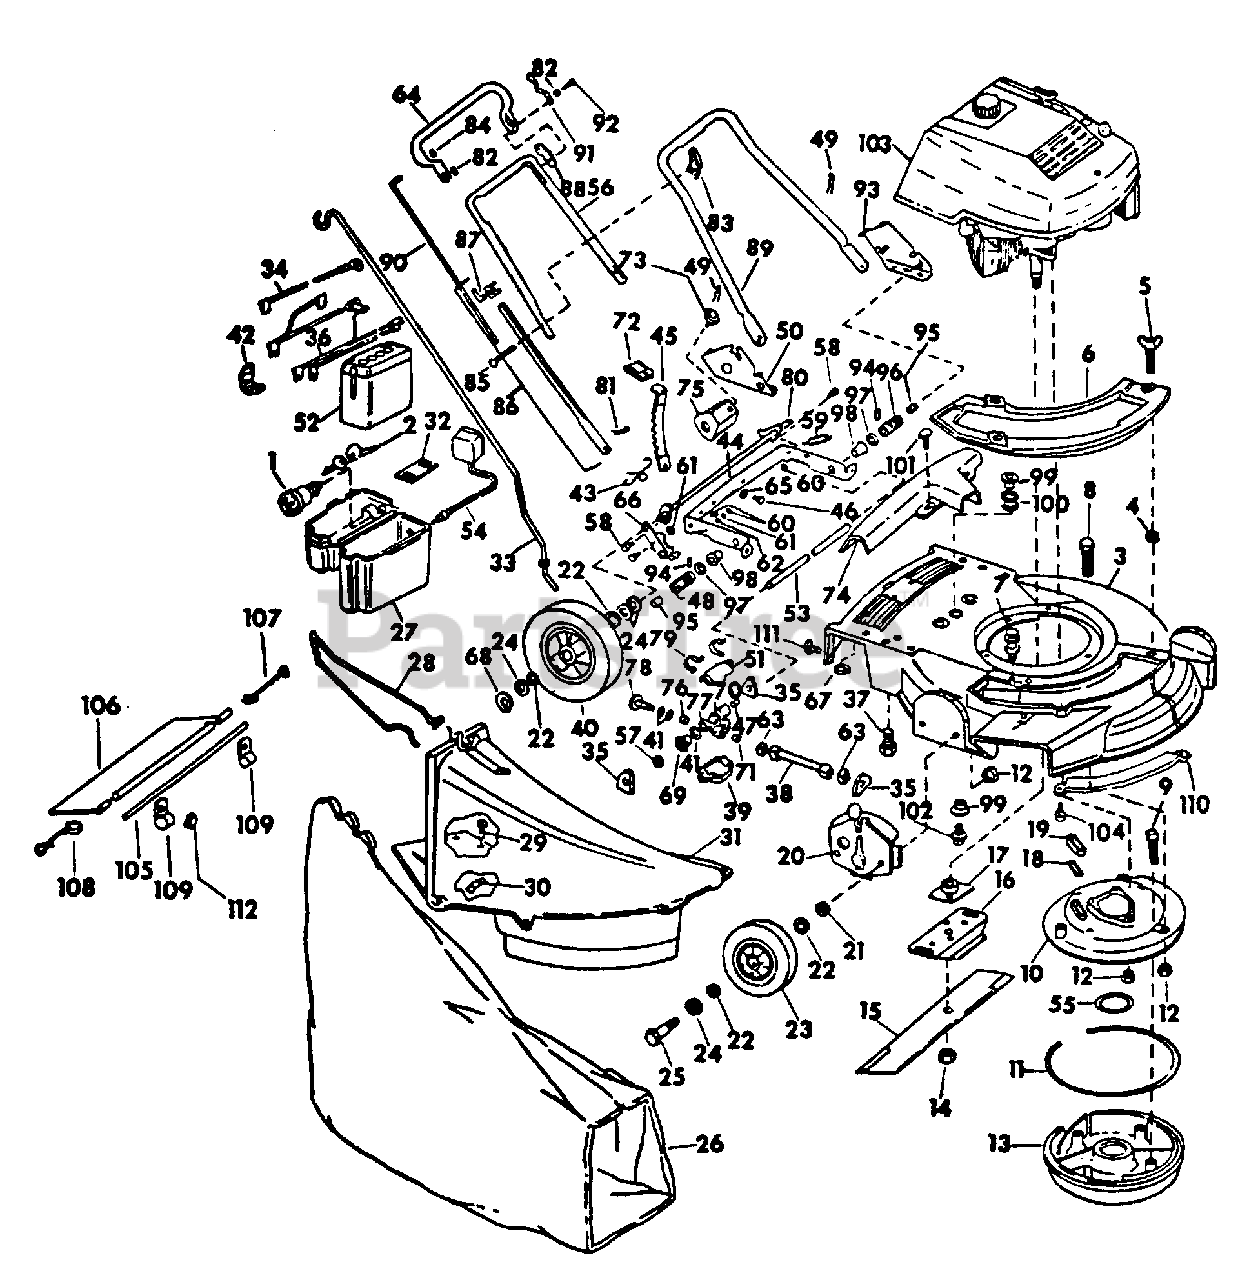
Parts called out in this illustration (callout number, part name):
3	HOUSING ASSY, 21 IN.
5	SCREW, WING
6	COVER, CHUTE OPENING
7	SCREW, SHOULDER
8	SCREW, MUFFLER PLT TO HSG
9	SCREW, MUFFLER TO PLATE
10	PLATE, MUFFLER
11	GASKET, MUFFLER OUTSIDE
13	COVER, MUFFLER
15	BLADE, 21 IN.
16	STIFFENER, BLADE
17	COLLAR & PLATE
18	GASKET, EXHAUST
19	SLEEVE, EXHAUST GASKET
20	ADJUSTMENT, HEIGHT
22	WASHER, FELT
23	WHEEL AND TIRE
24	WASHER, WHEEL BOLT HD
25	BOLT, WHEEL FRT SHOULDER
27	BOX, BATTERY
28	GUARD, WHEEL
31	CHUTE ASSY
32	STRAP, BATTERY BOX MTG
33	ROD, GRASS BAG
39	COVER, GEAR BOTTOM
40	WHEEL & TIRE, 8 IN. REAR
41	WASHER, THRUST
42	POD, INSULATION
43	SPRING, HEIGHT ADJ
45	LEVER, HGT ADJ
47	BEARING, NEEDLE
48	ROLLER, DRIVE RH
50	BRACKET, HANDLE RH
51	COVER, GEAR TOP
52	BATTERY, DRY CHARGED
54	CHARGER, TRICKLE
55	GASKET, MUFFLER INSIDE
56	HANDLE, CENTER
57	WASHER, FELT
58	BOLT, SHOULDER
64	HANDLE & GRIP
67	WASHER, BATTERY MOUNTING BRACKET
69	GEAR, DRIVEN
70	BRACKET & BRG ASSY
71	BEARING, NEEDLE
74	COVER, DRIVE
75	GUARD, ROLLER
76	BEARING, NEEDLE
77	BEARING, NEEDLE
78	GEAR, DRIVE
79	CLAMP, COVER
84	NUT, PUSH
86	LEVER ASSY, CONTROL
89	HANDLE, BOTTOM
90	ROD, CONTROL
91	KNOB & SPRING, LOCKOUT
92	BOLT, SHOULDER
93	BRACKET, HANDLE LH
94	PIN, ROLLER TO SHAFT
95	PLUG, ROLLER GREASE
96	ROLLER, DRIVE LH
97	WASHER
98	SLEEVE & BEARING
99	SPACER, FLANGED
101	SCREW, HEX-HD
103	ENGINE, IH
107	SPRING, SHIELD LH
108	SPRING, SHIELD RH
110	BAR, TOE - 21 IN.
111	SCREW, 1/4-20 X 5/8 ZND HEX-HD CAP
112	NUT, 1/4-20 HEX LOCK CAD.
